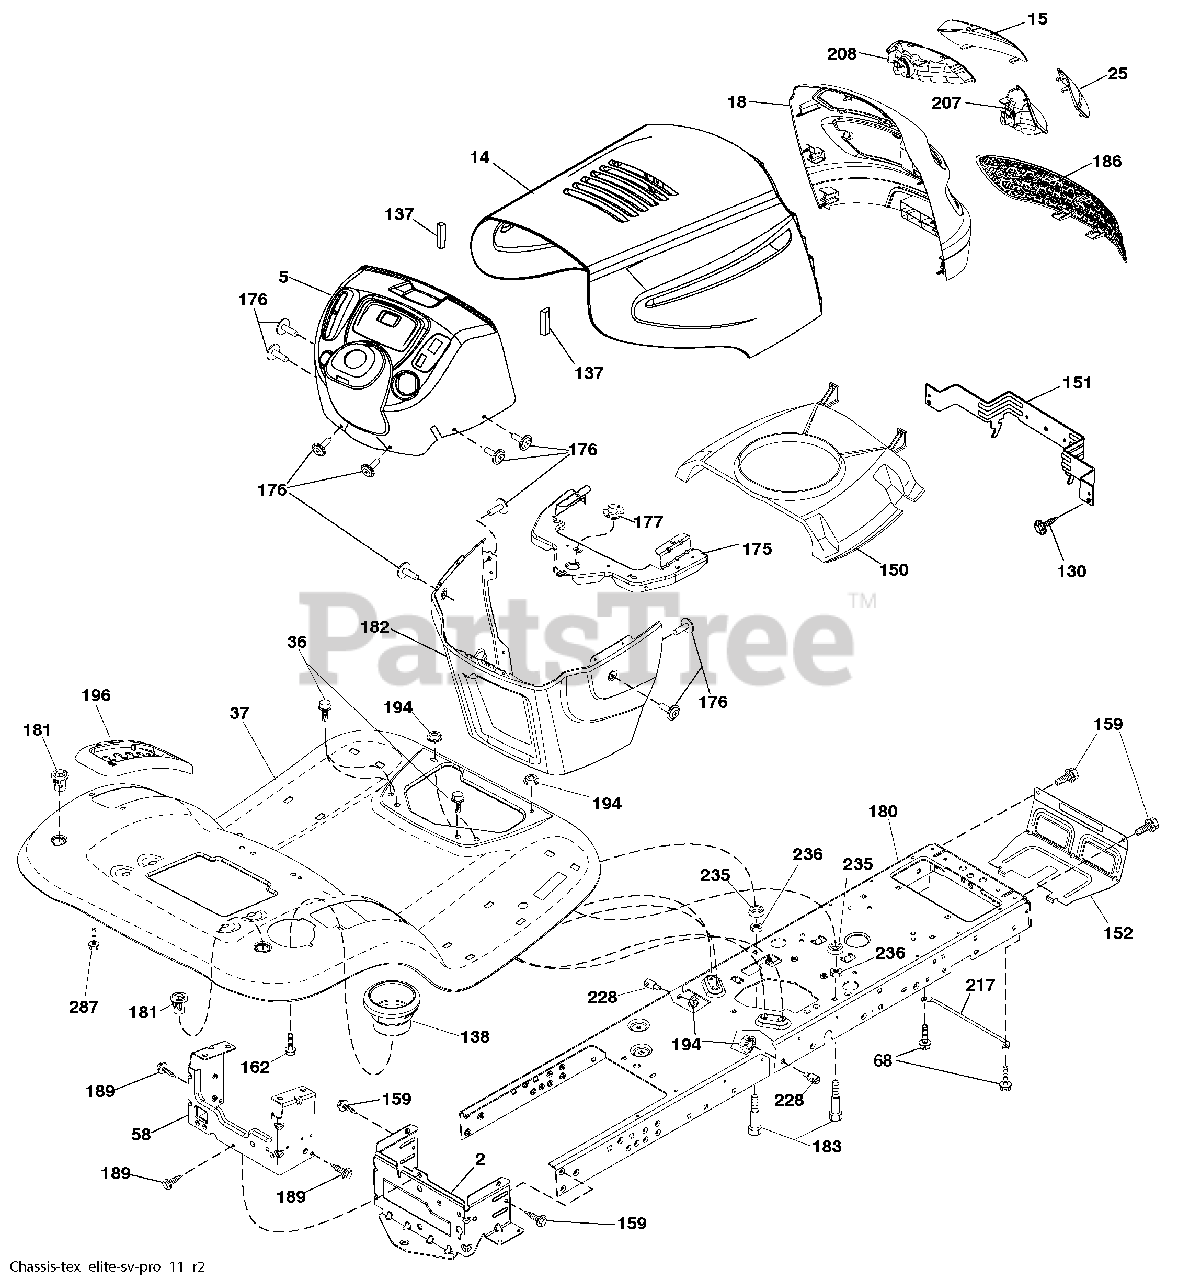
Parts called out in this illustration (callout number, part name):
2	Drawbar Lower
5	Dash
14	Hood
15	Lens Grille LH
18	Grille
25	Lens Grille RH
36	Screw 5/16-18 x 3/4
37	Fender
58	Drawbar Upper
68	Screw Thdrol 5/16-18 x 1/2
130	Screw #10 x 0.750
137	Bumper Hood
138	Cupholder
150	Duct Heat Hood
151	Bracket Pivot
152	Shield Browning/Debris
159	Screw Hexwsh Thdrol 3/8-16 x 3/4
162	Screw Hex Wsh Hi-Lo 1/4 x 1/2
175	Crossmember
176	Screw 10-24 x 5/8 Wshd Qdrx
177	Bushing Steering
181	Bushing Mtg. Fender Crgo.
182	Dash Lower
183	Bolt Fin Hex 5/16-18 x 1-1/4
189	Screw 5/16-18 x 3/4
194	Nut Lock Hex Flange 5/16-18
196	Console Asm. Deck Lift
207	Bezel Grille RH
208	Bezel Grille LH
217	Rod Pivot Hood
228	Stud Fastener
235	Spacer Fender
236	Nut Center Lock 5/16-18
287	Screw 1/4-20 x 3/8
